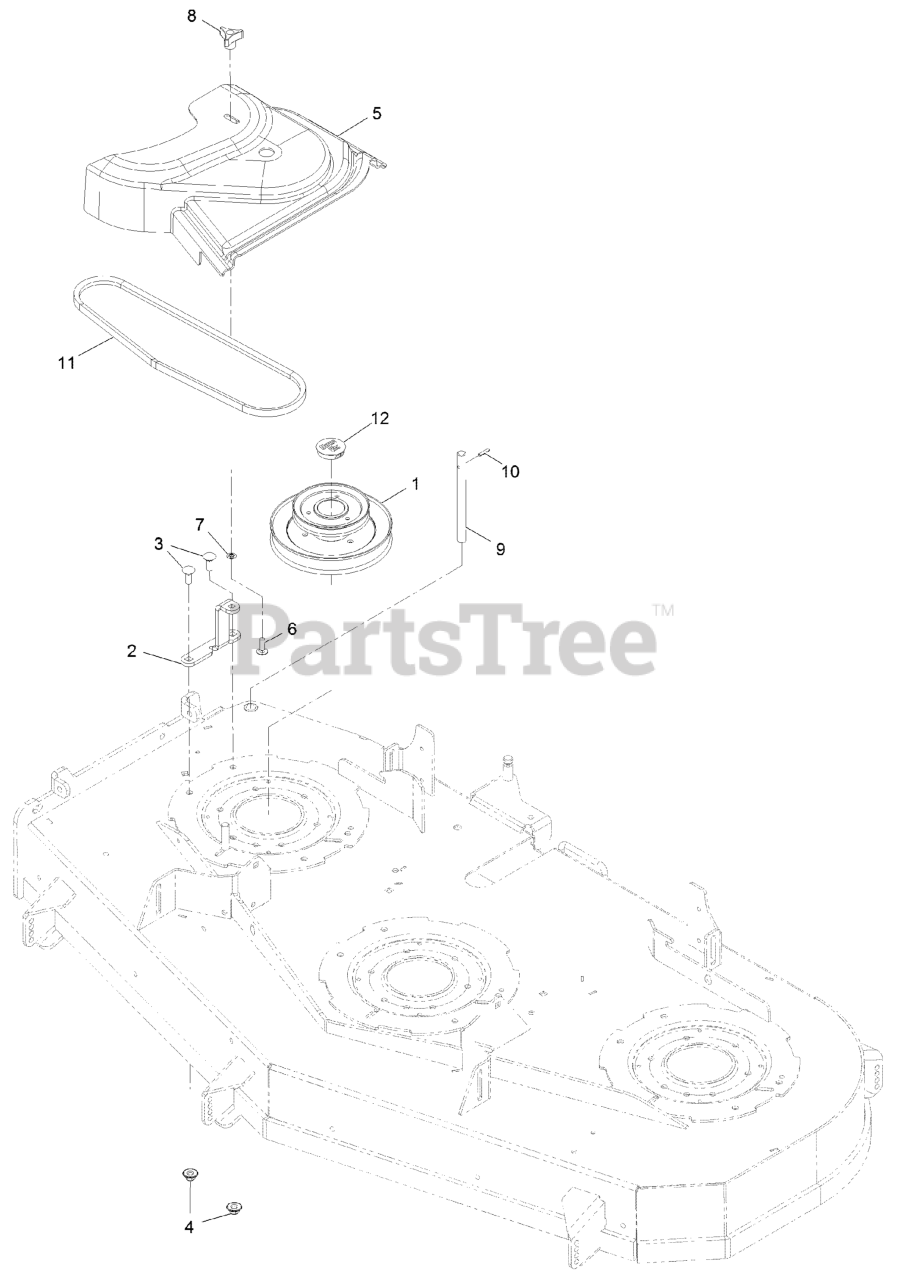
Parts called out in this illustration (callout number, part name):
1	JACKSHAFT,UV DRIVE 604 SPLINED
2	BRACKET-BELT COVER
3	BOLT-CARR
4	Nut-Nyloc 3/8-16 Flg
5	COVER-BELT, UV 60 ENTRY
6	BOLT-CARR
7	RING-RETAINING, BOLT
8	KNOB-3 PRONG
9	SHAFT-CATCHER, GRASS
10	PIN-ROLL
11	V-BELT (17569)
12	PLUG, BLACK NYLON 1.75
